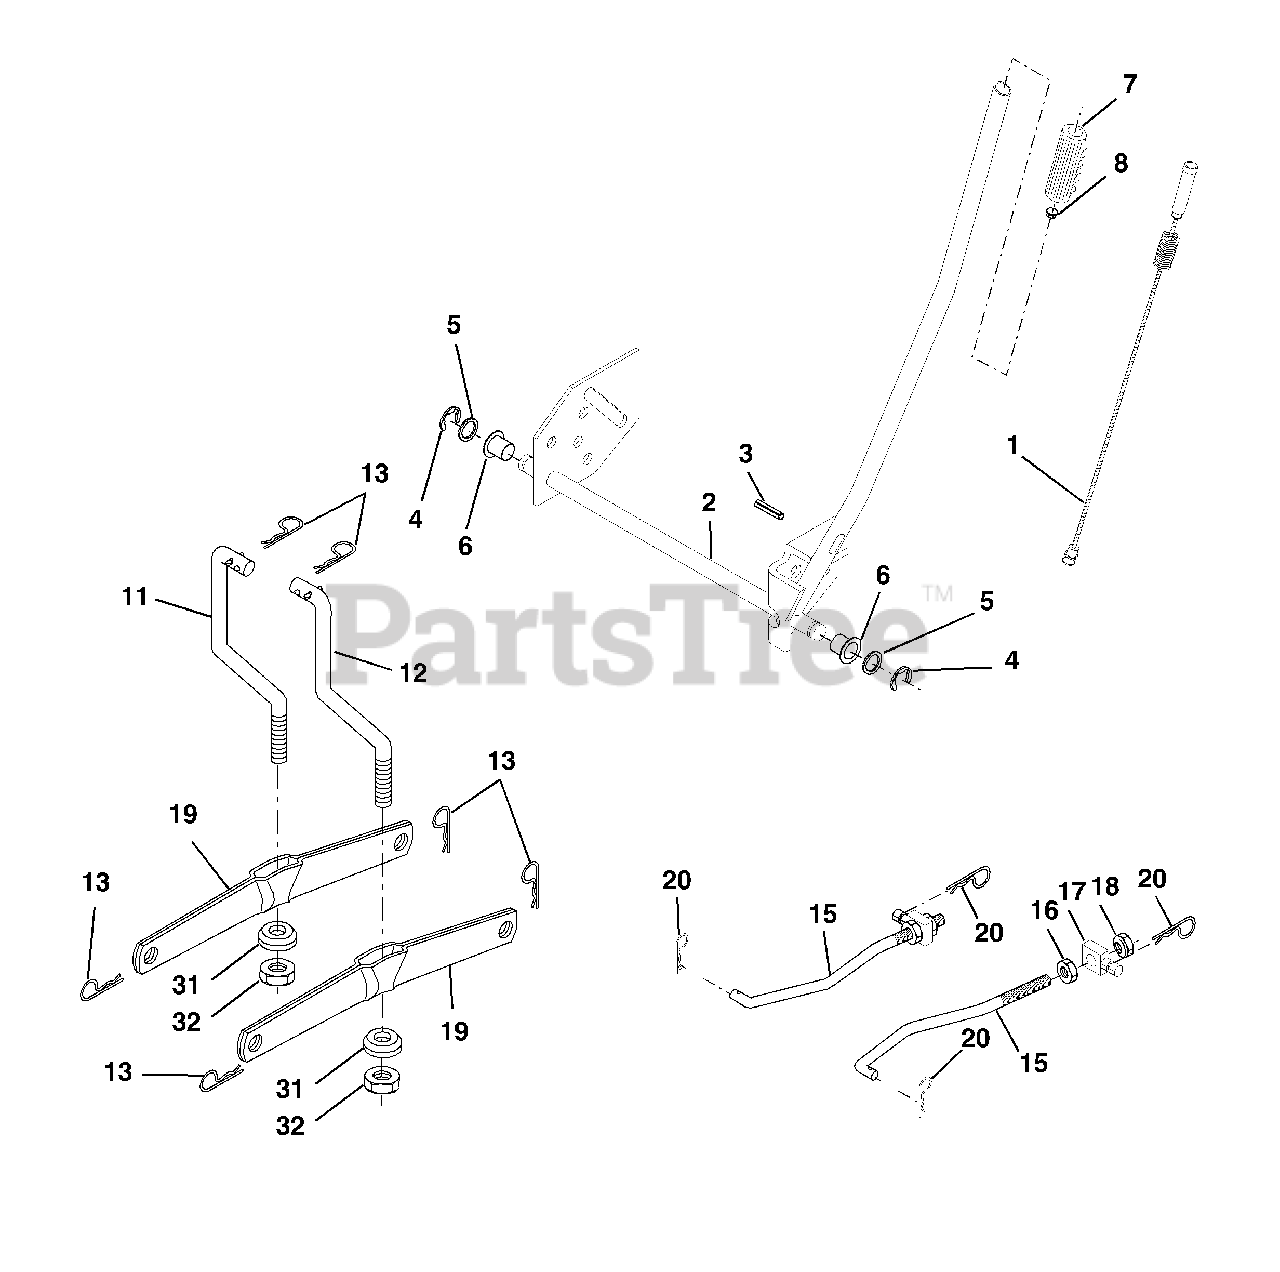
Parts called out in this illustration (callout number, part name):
1	Wire Asm Inner/Sprg w/plunger
2	Shaft Asm Lift RH
3	Pin Groove 1 500 Zinc
4	E Ring #5133-62
5	Washer 21/32 X 1 X 21 Ga
6	Bearing Nylon Blk 629 Id
7	Grip Handle Bicycle Matte Blk
8	Button Plunger Black
11	Link Lift LH Fixed Length
12	Link Lift RH Fixed Length
13	Retainer Spring
15	Link Front
16	Nut Jam Hex 1/2-13 Unc
17	Trunnion
18	Nut Lockw/Wsh 1/2-13 Unc
19	Arm Suspension Rear
20	Retainer, Spring
31	Bearing Pvt Lift
32	Nut Crownlock 3/8-24
